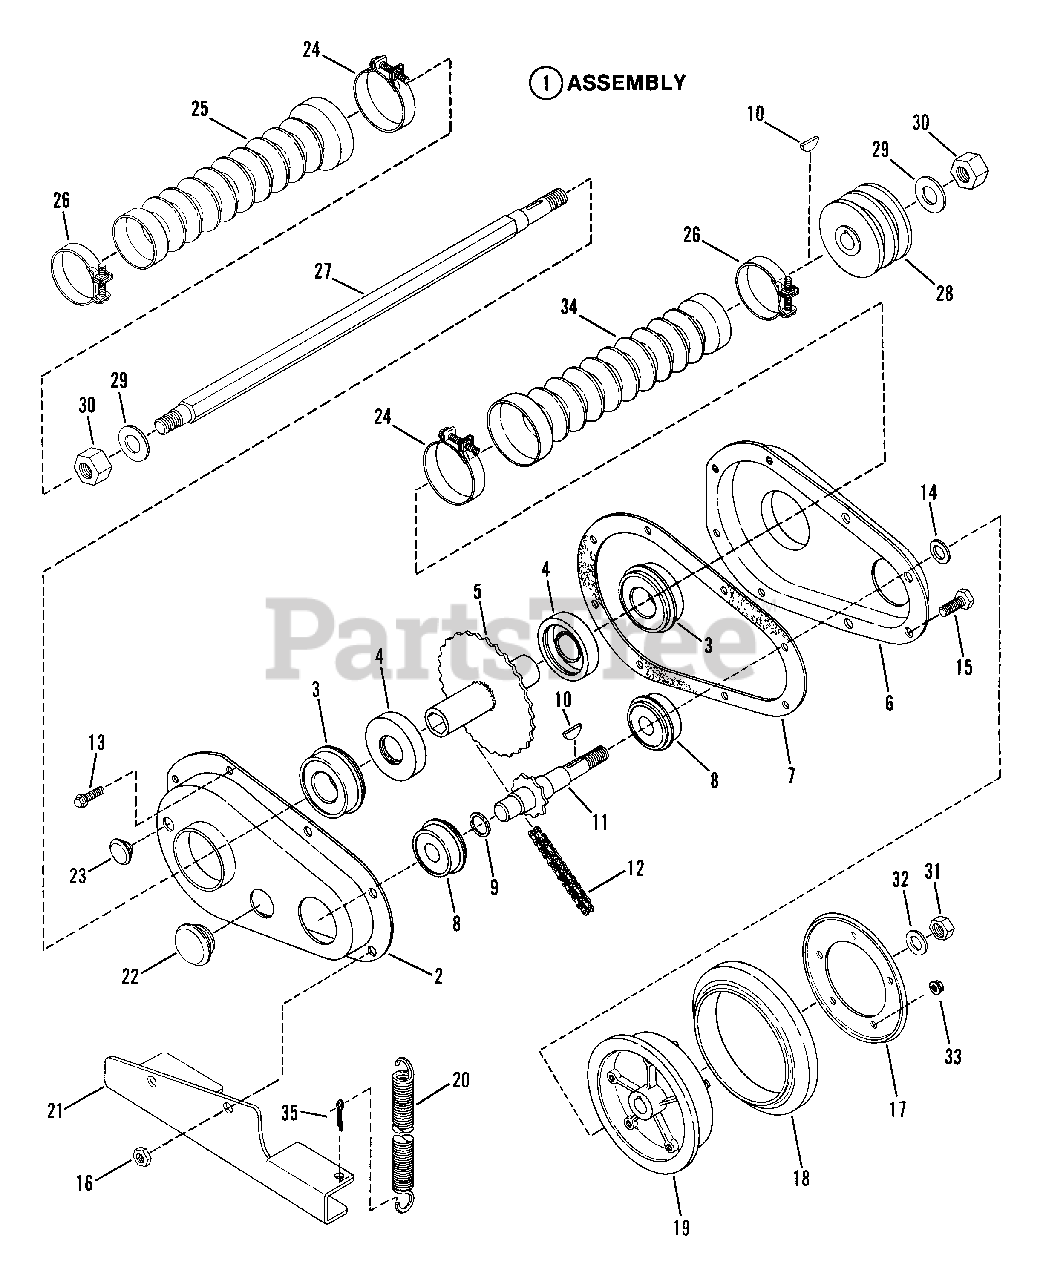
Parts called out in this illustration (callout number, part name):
1	ASSEMBLY, Chain Case
2	COVER, Chain Case, R.H.
3	BEARING, 3/4"
5	HUB & SPROCKET
6	COVER, Chain Case, L.H.
7	GASKET, Chain Case
8	BEARING
9	O-RING, 15/32
10	KEY, Woodruff, 3/32 x 1-1/2"
11	DRIVE SPROCKET
12	CHAIN
13	SCREW, #10-24 x 1/2" Hex Washer Self-Tap (Torx)
14	WASHER, 5/16"
15	SCREW, 1/4-28 x 1/2", Hex Head Cap
16	NUT, 1/4-28 Hex Lock
17	PLATE
18	RING, Rubber
19	HUB, Rubber Ring
20	SPRING
21	BRACKET, Shift
22	PLUG, 3/4"
23	PLUG, 3/8"
24	CLAMP, 1-7/8"
25	COVER, Shaft
26	CLAMP, 1-1/2"
27	SHAFT, Hex
28	PULLEY, V-Belt
29	WASHER, 7/16 SAE
30	NUT, 7/16-20 Hex Center Lock
31	NUT, 3/8-24 Hex Lock
32	WASHER, 3/8 Belleville
33	NUT, 1/4-20 Hex Flange Lock
34	COVER, Left Shaft
35	PIN, 5/32 x 1" Cotter
